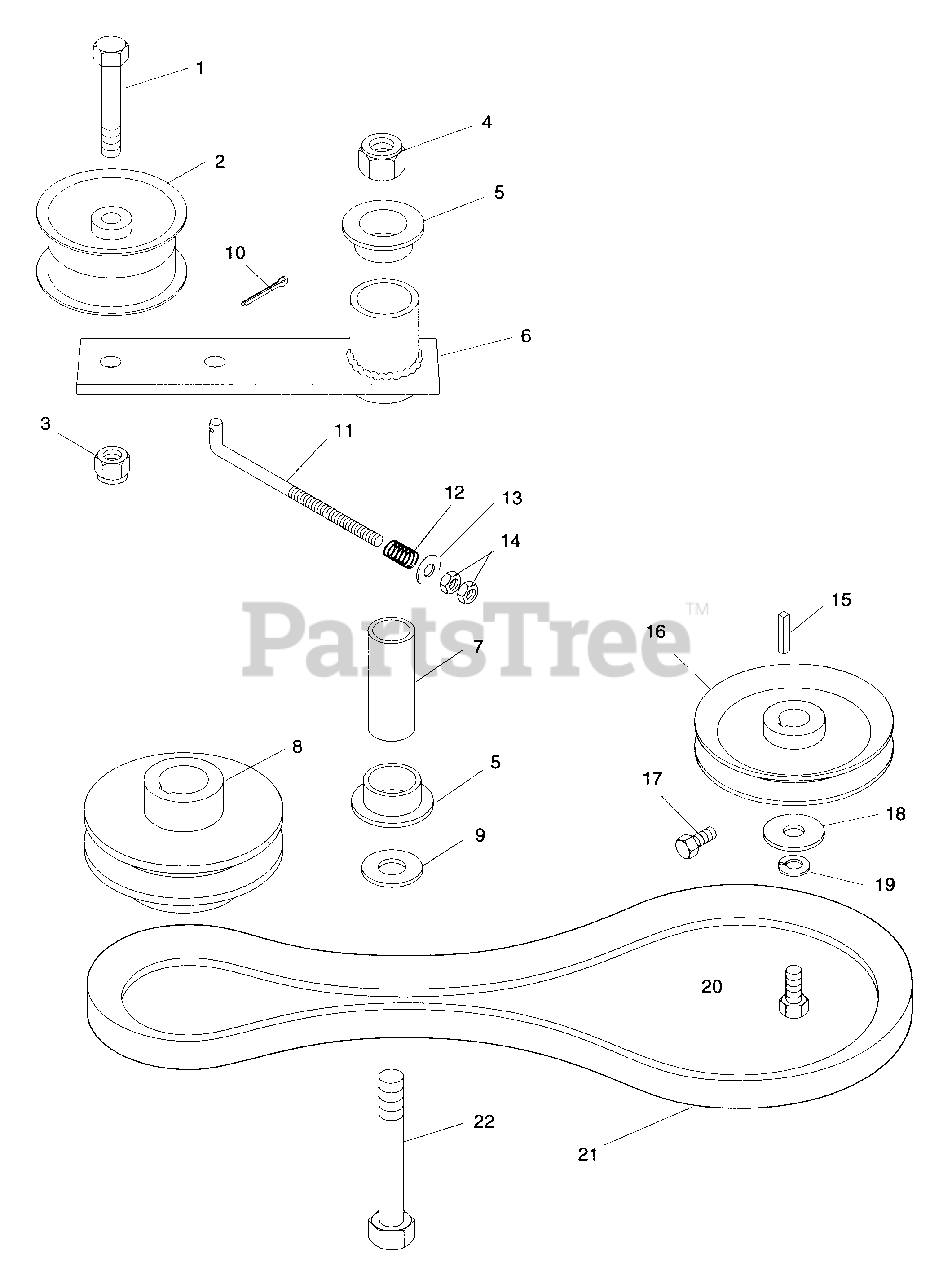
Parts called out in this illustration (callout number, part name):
1	Blt - Hex .38 - 16 x 1.75 Pl Gr 5
2	Idler - Ply
3	Nut - Lk - Nyl .375 - 16 Pl
4	Nut - Lk - Nyl .50 - 13 Pl
5	Bshg - Flg .762 x 1.0 x .580 x 1.48 Ny
6	Wldmt, Ground Drive Idler
7	Bush., 5.560 x.745 x 2.04 St
8	Sheave, Eng Ground Drive
9	Wshr - Fl - Stl .531 x 1.062 x .095
10	Pin - Cotr .09 x .75 Pl
11	Rod, Idler
12	Sg - Comp .188 x 1.66 x 2.0
13	Wshr - Fl - Stl .406 x .812 x .065 Pl
14	Nut - Hex .375 x 24 ZC
15	Key - Str 5mm x 25 mm x 5 mm
16	Sheave, Hyd Pump
17	Blt - Hex .25 x 20 x .50 Pl Gr 5
18	Wshr - Fl - Stl .281 x 1.250 x .062 Pl
19	Wshr - Lock .250 Reg.
20	Blt - Hex M6 x 1.0 x 12 mm Lg
21	V-Belt Eng To Pump
22	Blt - Hex .50 - 13 x 3.00
